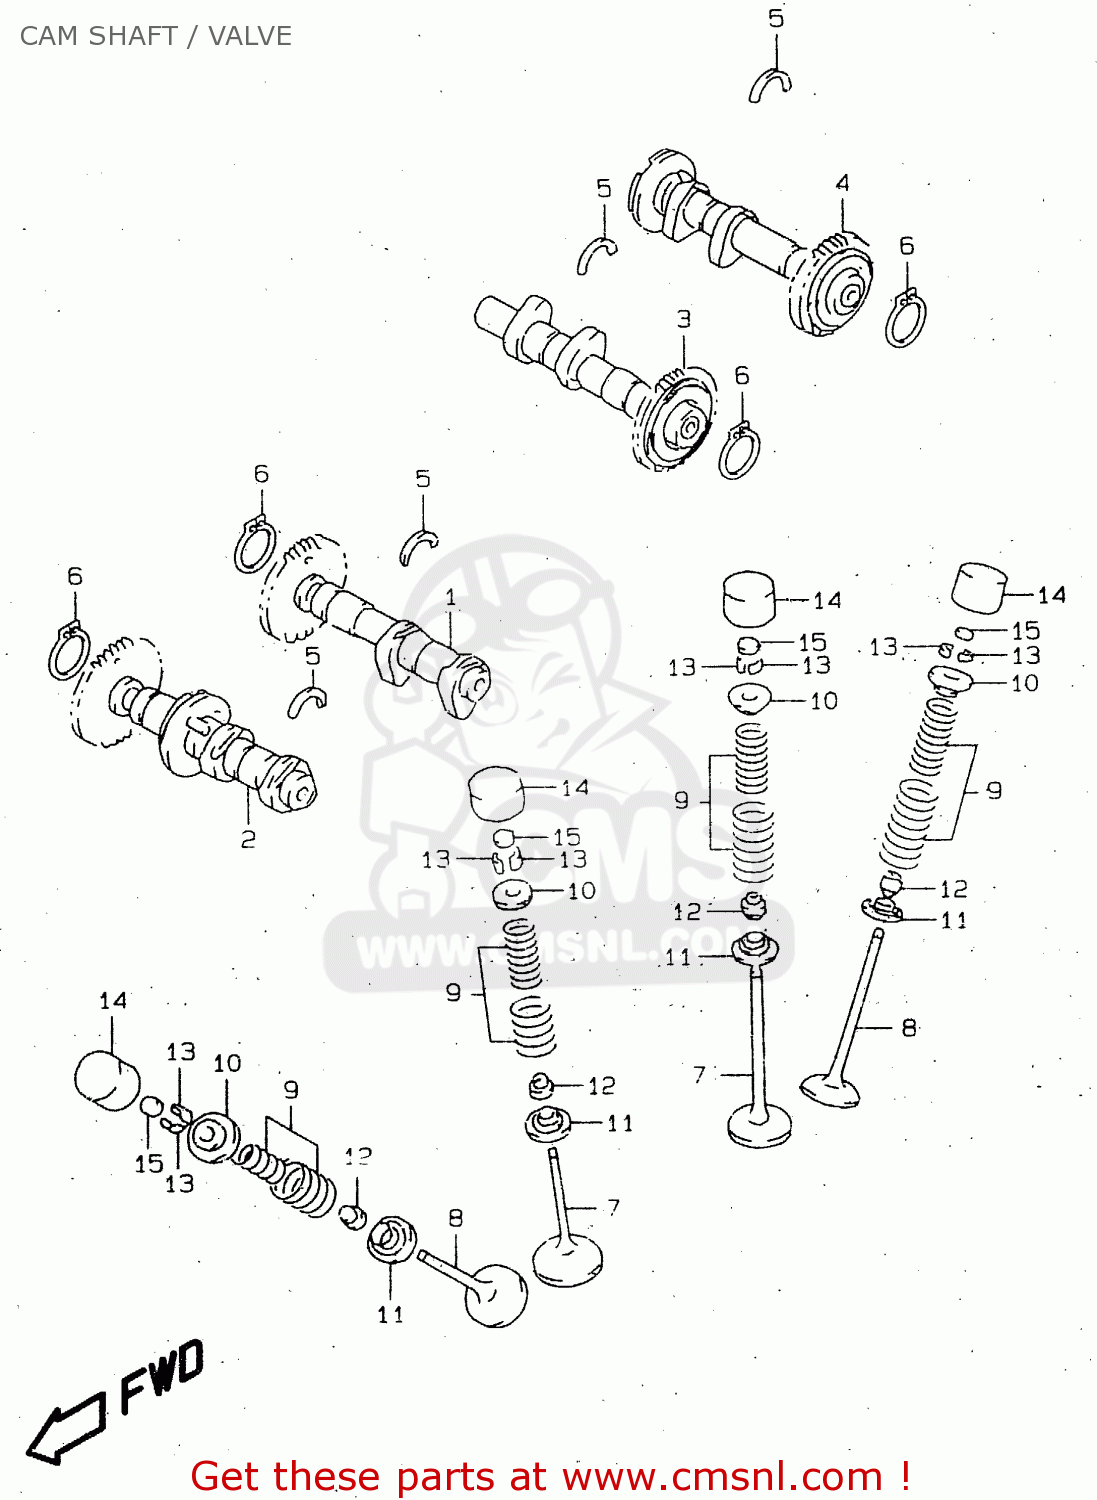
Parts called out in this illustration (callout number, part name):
1	CAMSHAFT ASSEMBLY,INTAKE,FRONT
2	CAMSHAFT ASSEMBLY,EXHAUST
3	CAMSHAFT ASSEMBLY,INTAKE,REAR
4	CAMSHAFT ASSEMBLY,EXHAUST
5	C RING
6	CIRCLIP
7	VALVE,INTAKE
8	VALVE,EXHAUST
9	SPRING SET,VALVE
10	RETAINER,VALVE SPRING
11	SEAT,VALVE SPRING
12	SEAL,OIL(5.5X11X8.2)
13	COTTER,VALVE
14	TAPPET
15	SHIM,TAPPET(T:2.3)
17	CASE,TAPPET SHIM
